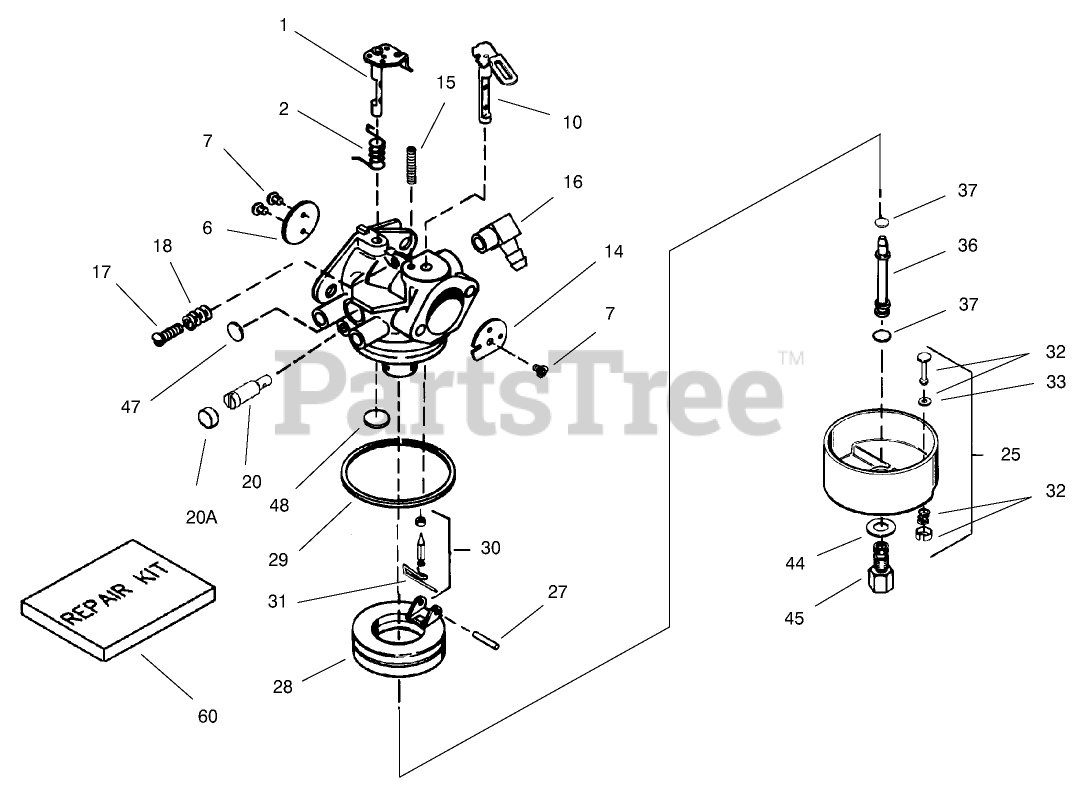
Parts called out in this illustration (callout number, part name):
1	Throttle Shaft Lever ASM
1A	Bushing
2	Spring-Return, Throttle
6	Throttle Shutter
7	Screw-Shutter
10	Choke Shaft Lever ASM
14	Choke Shutter
15	Spring-Positioning, Choke
16	Fitting-Fuel
17	Screw-Throttle Crack and Idle Speed
18	Spring-Tension
20	Screw-Restrictor, Idle
20A	Cap-Screw, Idle Restrictor
25	Float Bowl ASM (Incl. Ref. #32 and 33)
27	Shaft-Float
28	Float
29	O Ring-Bowl, Float
30	Inlet Needle, Seat Clip Assy. (Incl. No. 13)
31	Clip-Spring
32	Plunger Assy., Drain (Incl. Ref. 18)
33	Gasket-Plunger, Drain
36	Tube-Nozzle, Main
37	O-Ring
40	High Spee Bowl Nut.
44	Washer-Nut, Bowl
47	Plug-Welch, Idle Mixture Well
48	Plug-Welch, Atmospheric Vent
60	Repair Kit
